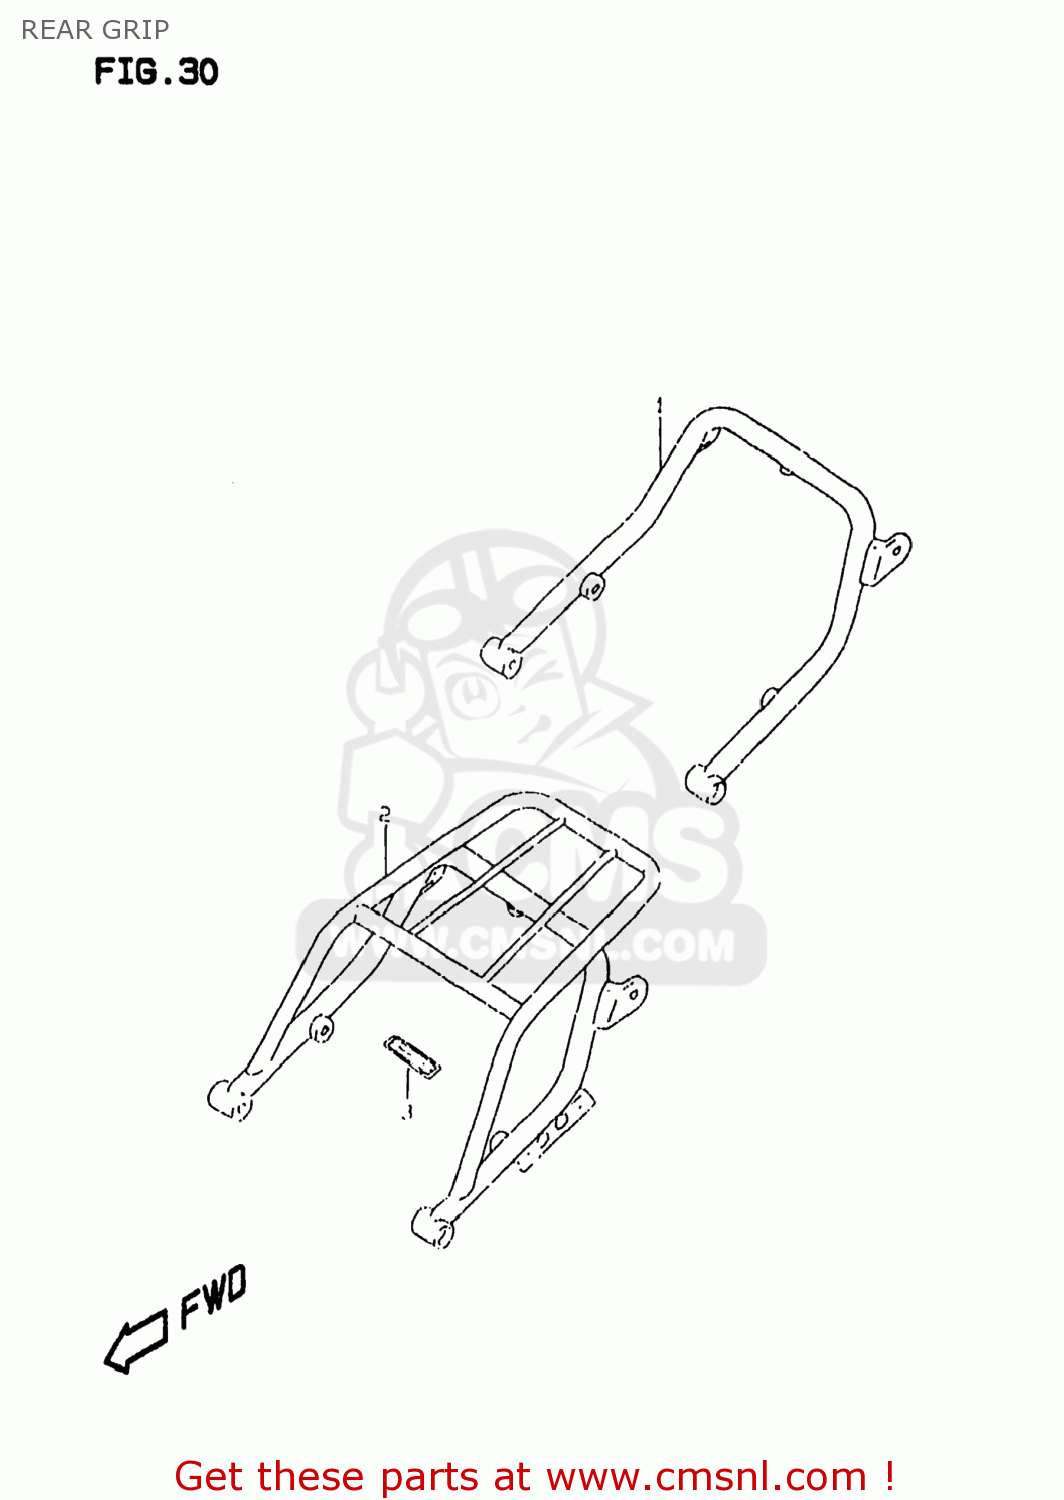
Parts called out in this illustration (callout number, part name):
1	GRIP,RR
2	CARRIER,SPORT
3	LABEL,WARNING
